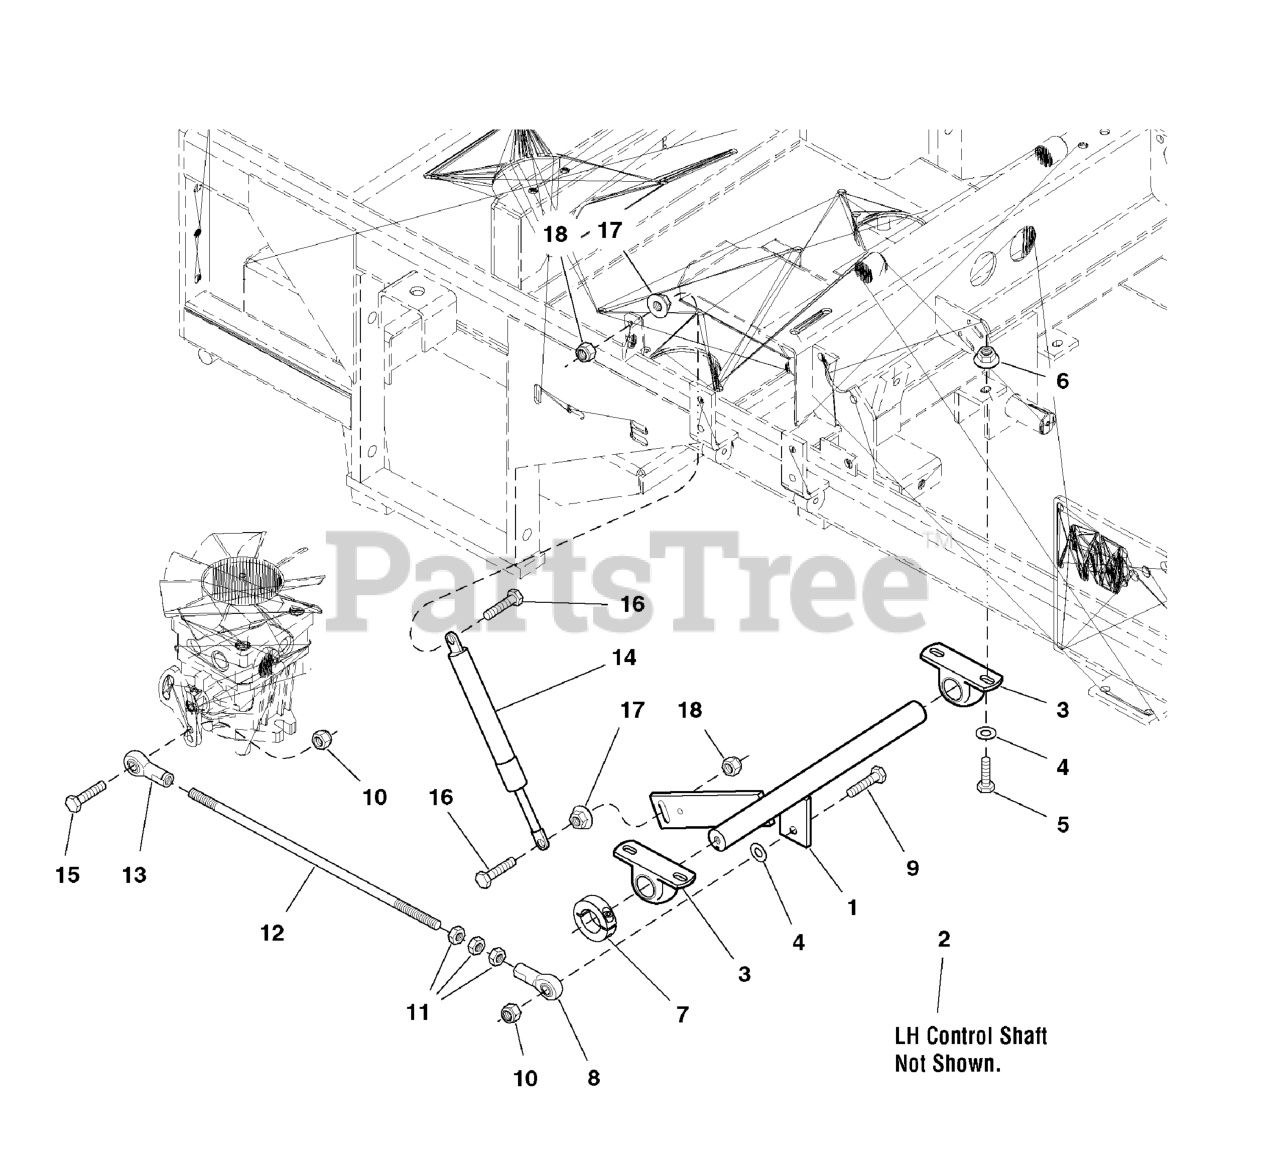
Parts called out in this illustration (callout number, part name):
1	CONTROL SHAFT-RH
3	BEARING, Pillow Block
4	WASHER, 5/16" SAE
5	BOLT, 5/16-18 X 1 GD5 YZ
6	NUT, 5/16-18 HEX SERRATED FLANGE (SMALL)
7	COLLAR, 1" Split
8	BALL JOINT 5/16-24 RH FEMALE BRONZE RACE
9	BOLT, 5/16-18 x 1-1/4
10	NUT, 5/16-18 Hex Nylon Lock
11	NUT, 5/16-24 Hex
12	HYDRO LINKAGE ROD
13	BALL JOINT 5/16-24 LH FEMALE BRONZE RACE
14	DAMPENER
15	BOLT, 5/16-18 x 1-1/8
16	BOLT, M8 x 30MM
17	NUT, M8-1.25 Hex Serrated Flange
18	NUT, M8-1.25 Hex Nylon Lock
